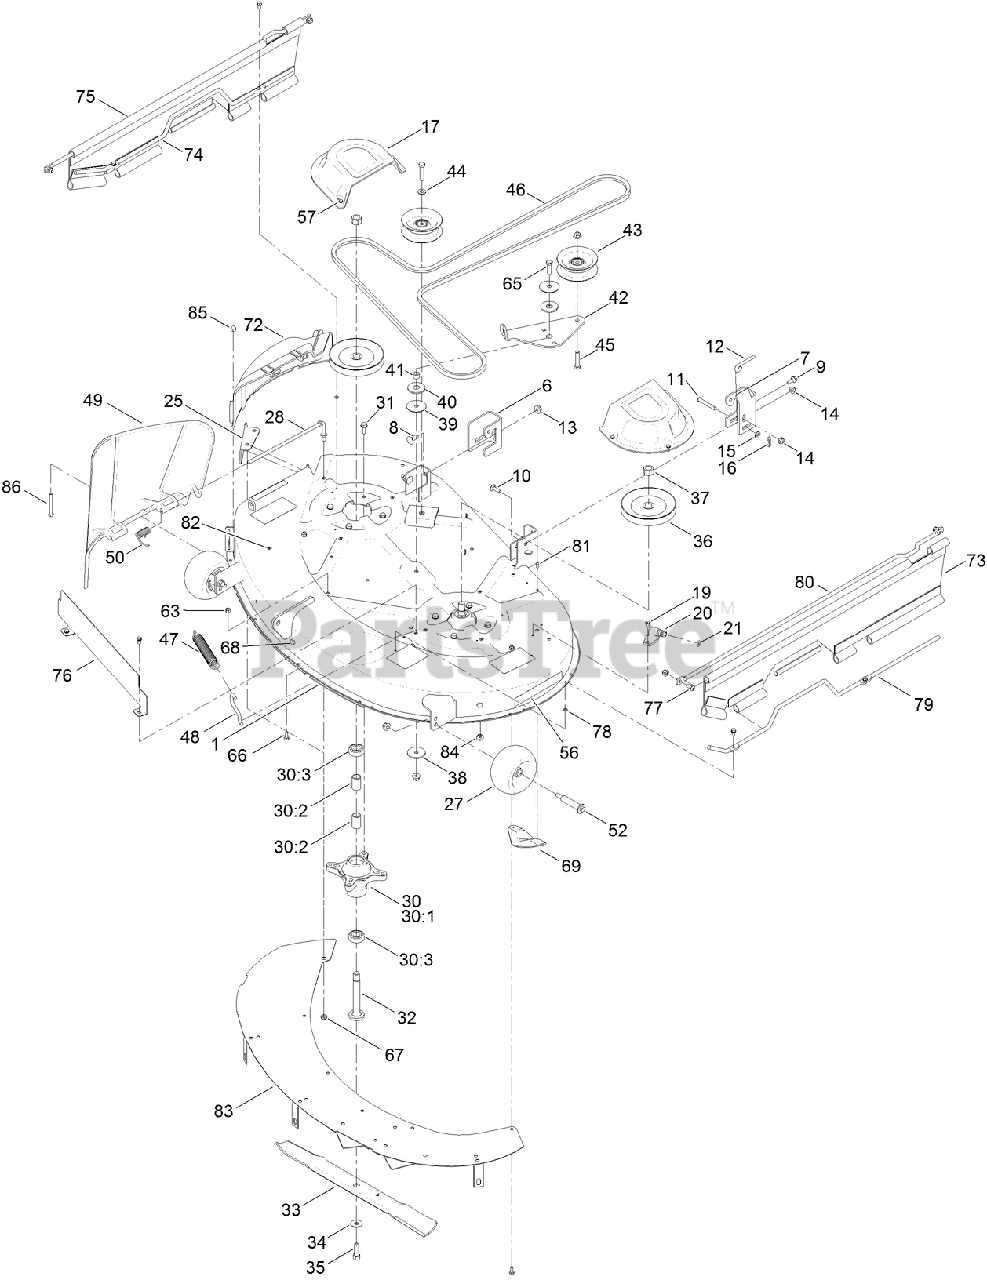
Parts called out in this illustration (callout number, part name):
1	42 INCH DECK AND DECAL ASM
6	BRACKET-HANGER, RH
7	BRACKET-HANGER, LH
8	BOLT-CARR
9	SCREW-SHOULDER,HWH
10	SCREW-CARR
11	PIN-CLEVIS
12	ROD-LEVEL, DECK
13	NUT-HF, NI
14	NUT-HF, NI
15	WASHER-PLAIN
16	PIN-COTTER
17	COVER-BELT
19	SCREW-HWH
21	O-RING
25	BAFFLE-CUTOFF
27	ROLLER-SCALP, ANTI
28	ROD-PIVOT
30	SPINDLE ASM
30:2	SPACER
30:3	BEARING-BALL
31	SCREW-TAPTITE
32	SHAFT-SPINDLE
34	WASHER-BELLEVILLE
35	SCREW-HH
36	PULLEY
37	NUT-HEX
38	WASHER-REBOUND
39	WASHER
40	WASHER-FRICTION, COMPOSITE
41	SPACER
42	ARM-IDLER
44	WASHER-FLAT
45	SCREW-HH
46	V-BELT
47	SPRING-EXTENSION
48	HOOK-RETURN, SPRING
49	DEFLECTOR
50	SPRING-TORSION
52	BOLT-SHOULDER
56	DECAL-RECYCLER
57	SCREW-TAPTITE
63	NUT-LOCK, NI
65	SCREW-HH
66	SCREW-HH
68	SCREW-HH
69	PLATE-KICKER
72	COVER-DISCHARGE
73	ROD-SUPPORT, UPPER
74	ROD-SUPPORT, LOWER (RH)
75	RH GUARD SIDE
76	SHIELD-FRONT, DECK
77	SCREW-HSBH
78	NUT-RETAINING
79	ROD-SUPPORT, LOWER (LH)
80	GUARD-SIDE, LH
81	SCREW-PPH
82	NUT-RETAINING
83	BAFFLE UPPER ASM
84	NUT-HF
85	NUT-CAP
86	SCREW-HH
